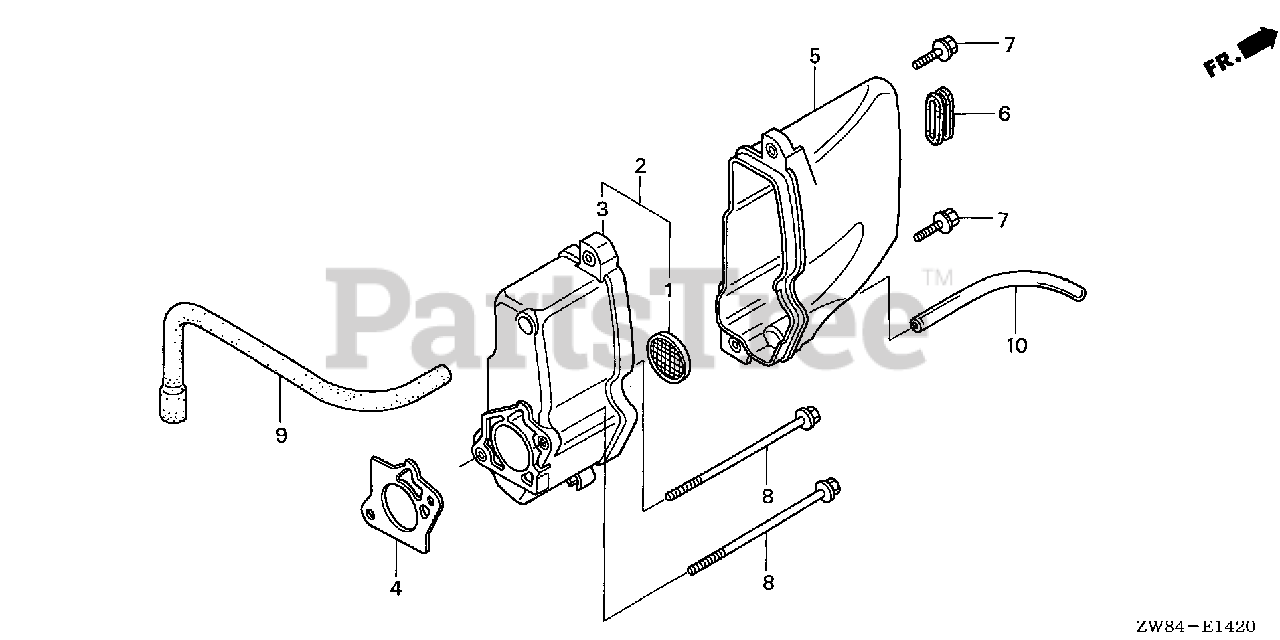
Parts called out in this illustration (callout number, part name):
1	TRAP, FLAME
2	PLATE ASSY., MUFFLER (NA USE ALT:04102-ZW9-000)
2	PLATE ASSY., MUFFLER
3	PLATE, MUFFLER (NA USE ALT:04102-ZW9-000)
3	PLATE, MUFFLER
4	GASKET, MUFFLER PLATE
5	COVER, MUFFLER
6	RUBBER A, TANK MOUNTING
7	BOLT, FLANGE (6X22)
8	BOLT, FLANGE (6X98)
9	TUBE, BREATHER
10	BULK HOSE, VINYL (3.5X6.5X8000) (3X6X90)
